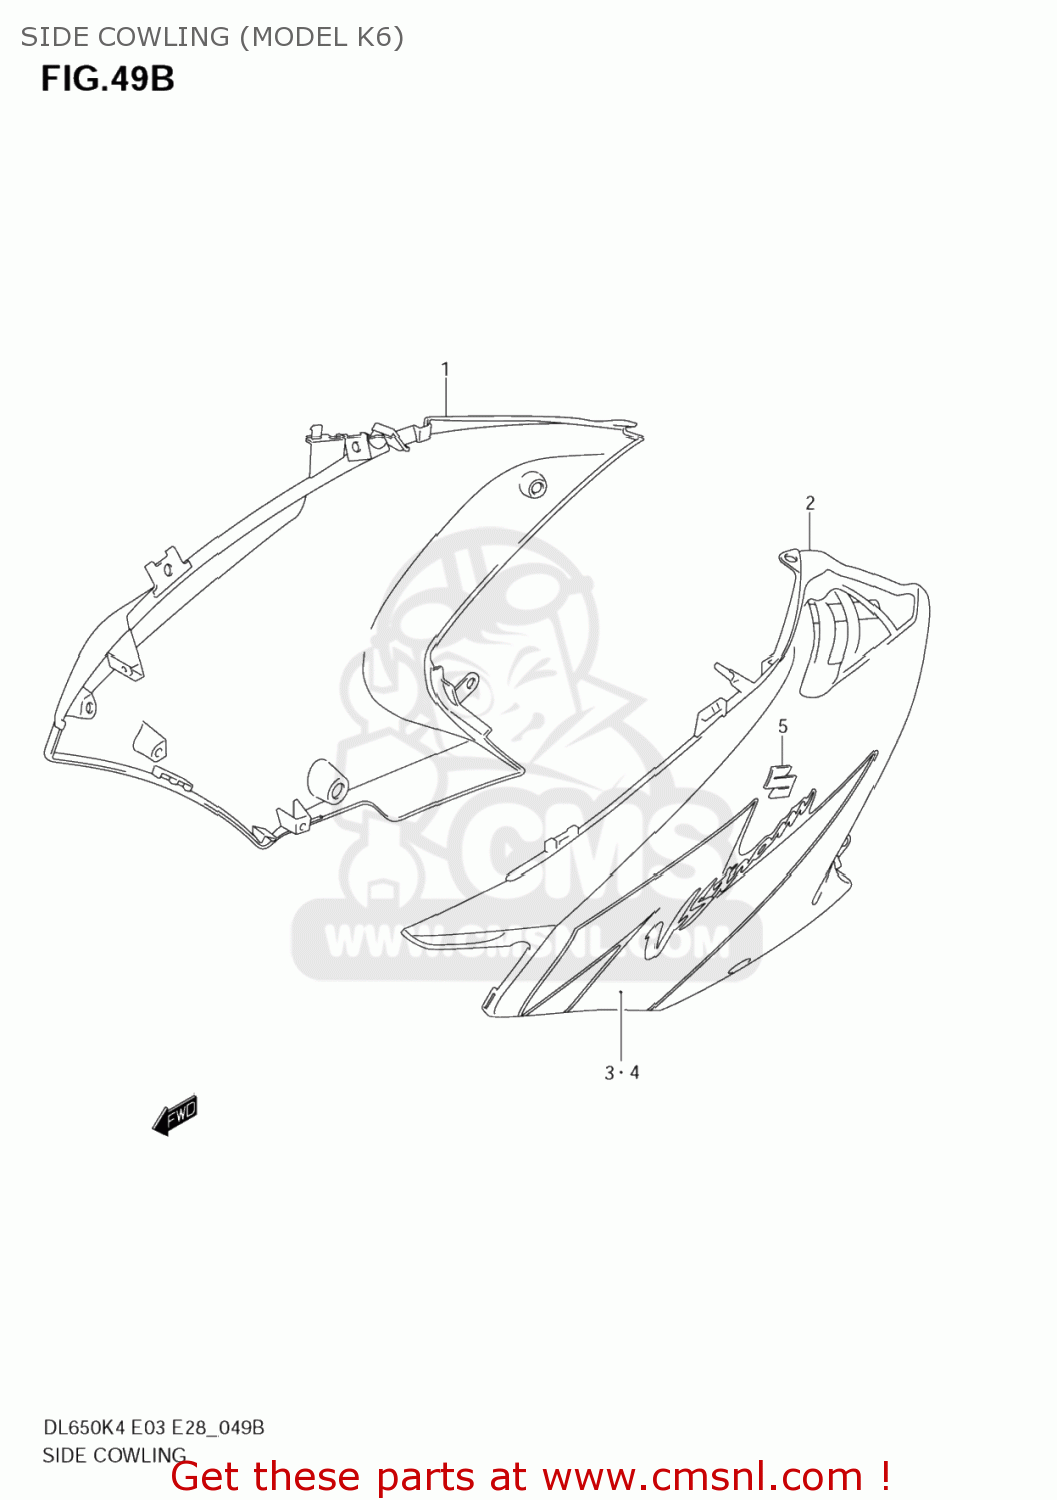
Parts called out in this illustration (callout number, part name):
1	COWLING ASSY,SIDE,R
2	COWLING ASSY,SIDE,L
3	TAPE,COWL SIDE,R
4	TAPE,COWL SIDE,L
5	EMBLEM,S
